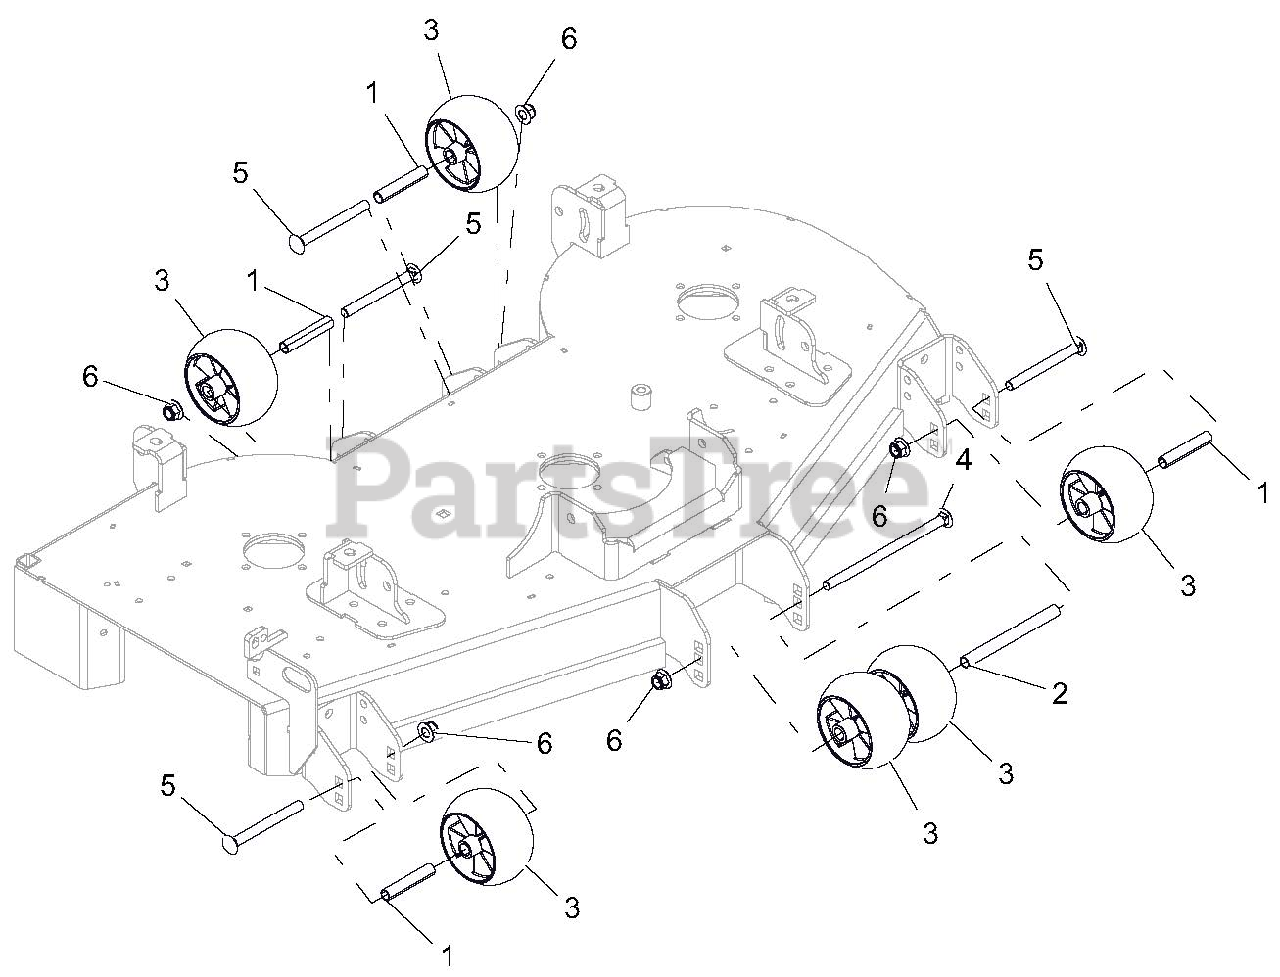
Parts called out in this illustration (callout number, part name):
1	SPACER, .510X.625X3.35
2	SPACER, .510 X .625 X 6.50
3	ANTI-SCALP WHEEL - 5X3 CTR
4	BLT-RDHDSQNK .50-13X8.50 Y
5	BLT-RDHDSQNK .50-13X5.00 G5 YWZC
6	NUT-LK-NYL-FLG .50-13 YWZC
